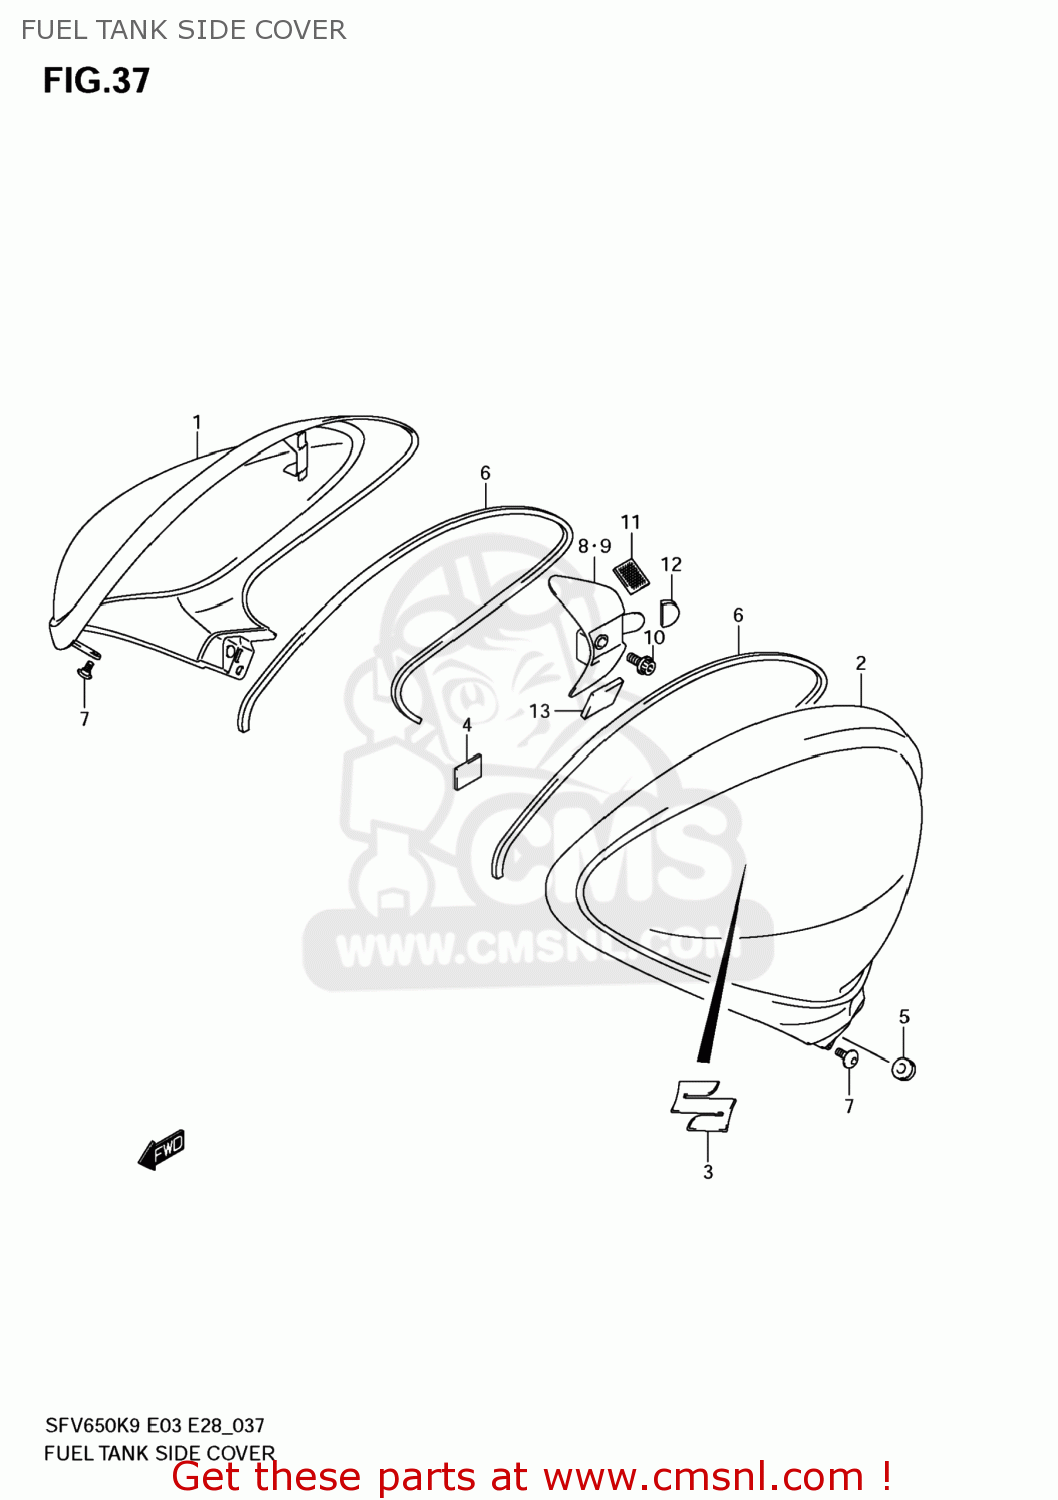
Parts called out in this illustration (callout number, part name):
1	COVER,FUEL TAN
2	COVER,FUEL TAN
3	EMBLEM,S
4	FASTENER
5	CUSHION
6	CUSHION,FUEL TANK SIDE COVER
7	BOLT(5X13)
8	BRACKET,FUEL TANK COVER,R
9	BRACKET,FUEL TANK COVER,L
10	BOLT
11	FASTENER
12	CUSHION
13	CUSHION,TANK SIDE COVER
